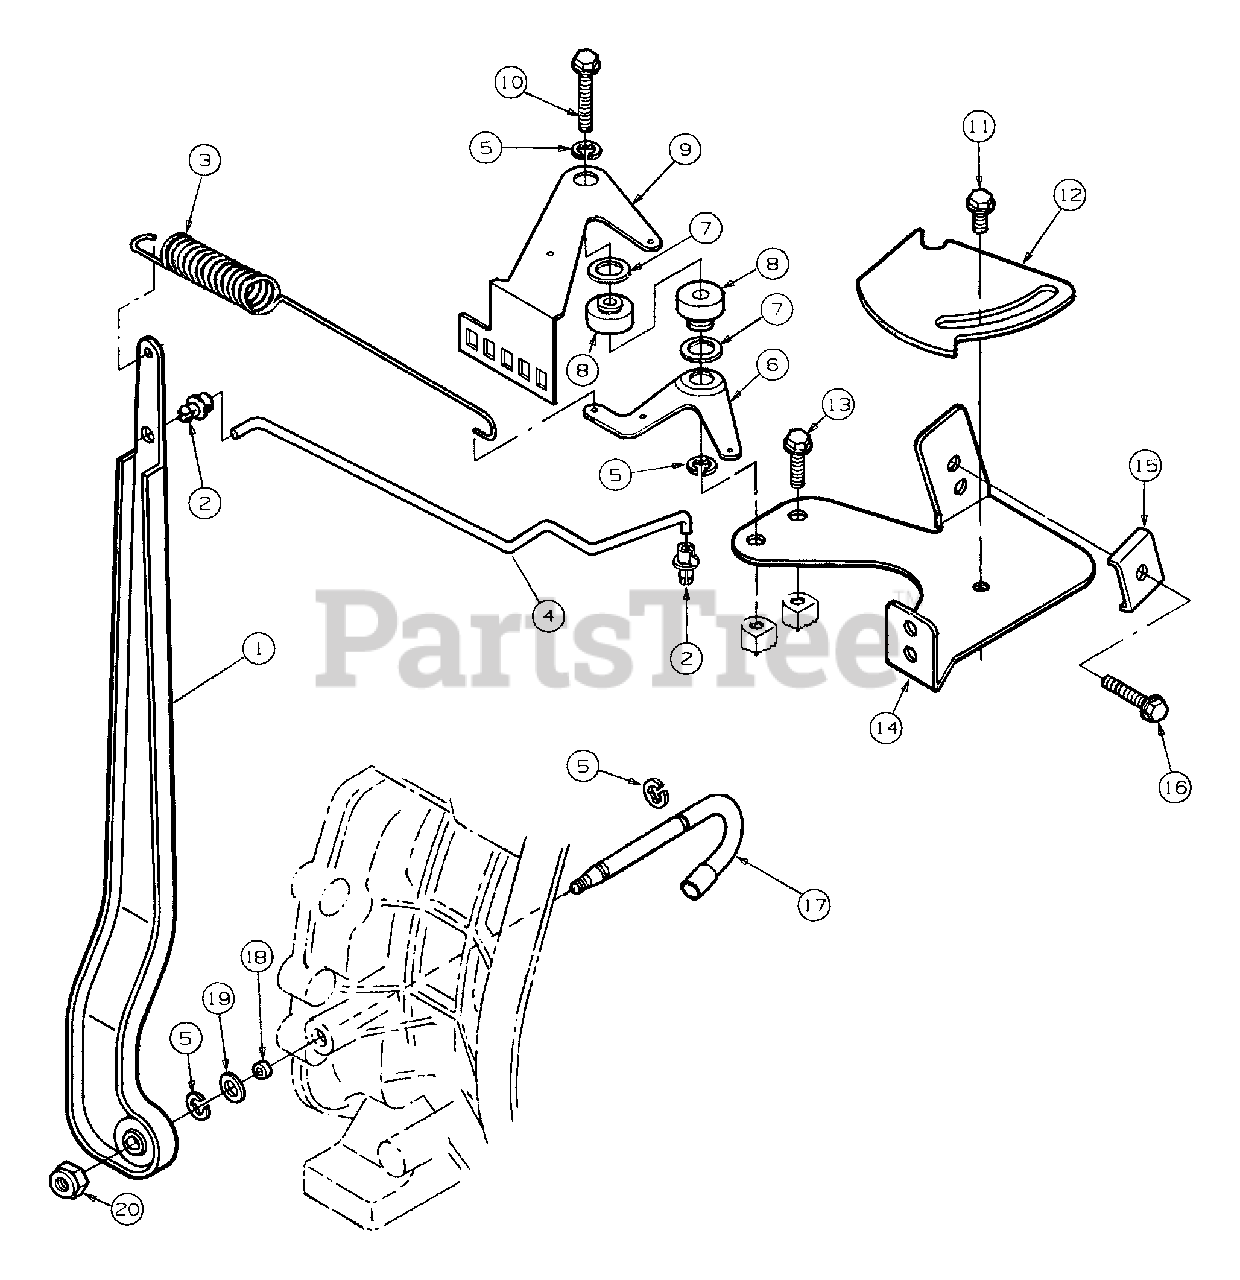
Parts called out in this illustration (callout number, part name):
1	Lever, Governor
3	Spring, Governor
4	Link, Throttle
6	Lever, Control
7	Washer, Wave Spring, M5
8	Pivot, Lever
10	Screw Hex Flange M5 x .8 x 30
11	Screw, Hex Flange, M5 x .8 x 10
12	Bracket, Throttle Stop
13	Screw, Hex Flange, M5 x .8 x 16
14	Bracket, Throttle Lever
16	Screw, Hx Hd TT #10-32 x 7/8
17	Shaft, Governor Lever
18	Seal, Governor Shaft Lever
19	Washer, Flat, M8
20	Nut Nylon Lock
